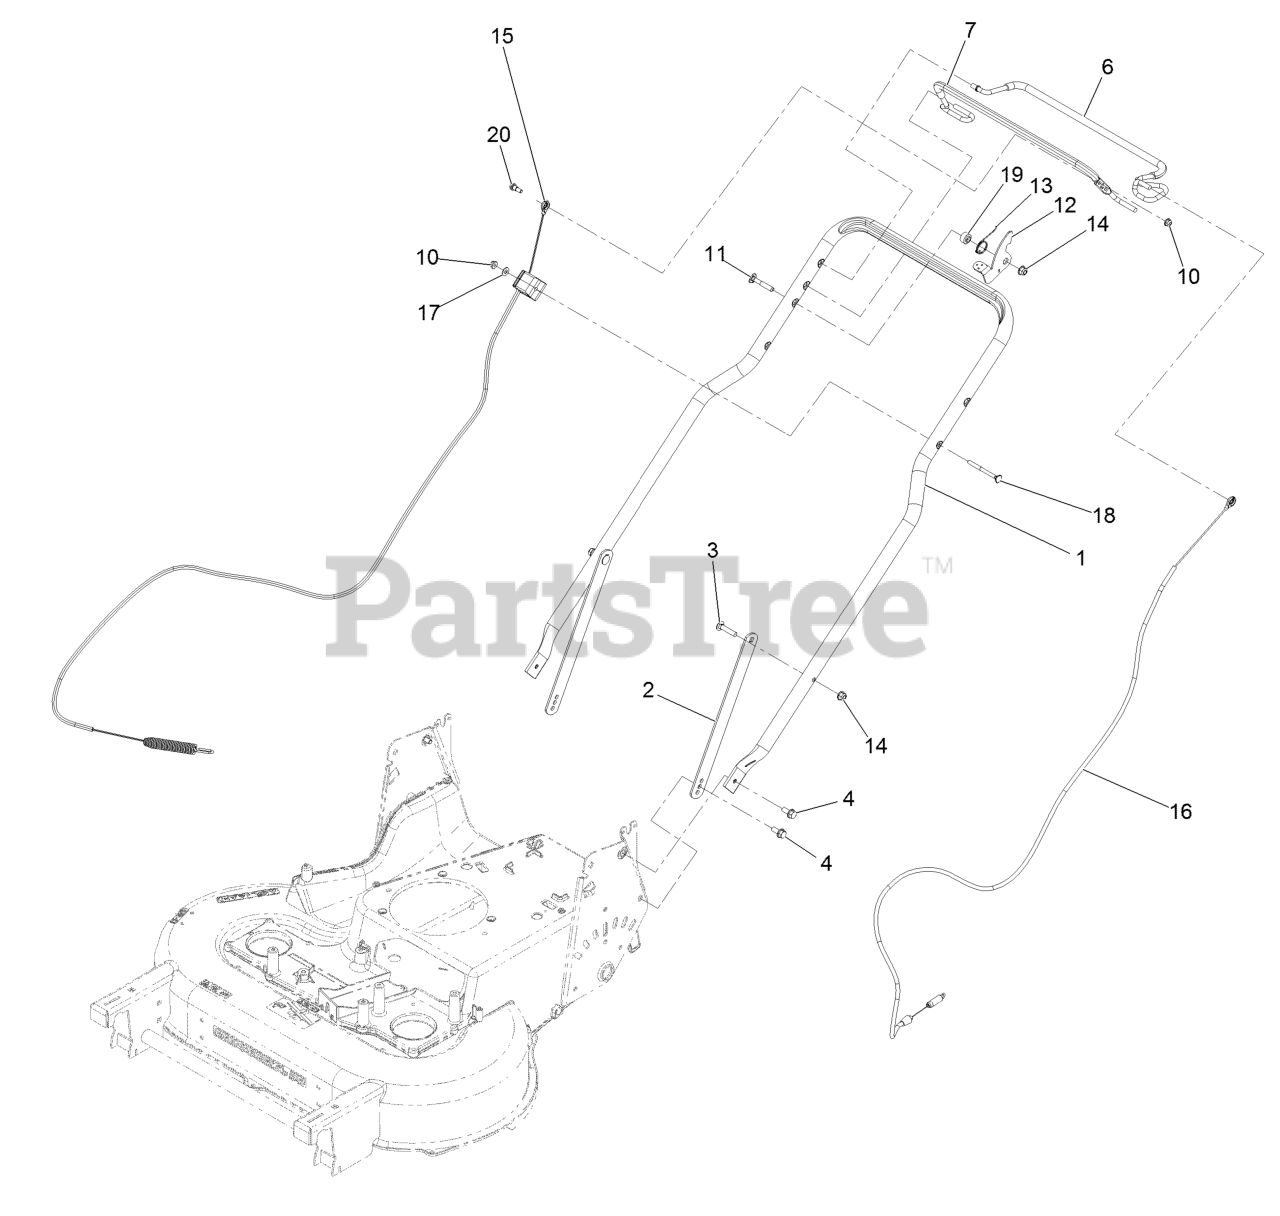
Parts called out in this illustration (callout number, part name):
2	Support-Handle
3	Bolt-Carriage 5/16-18 X 1 1/2
4	Screw-HHF
6	Bail-Traction, Coated
7	Bail-BBC, Coated
10	Nut-Nyloc 1/4-20 Flg
11	Bolt-Carriage 5/16-18 X 2
12	Lever-BBC
13	Spring-Lever, BBC
14	Nut-Nyloc 5/16-18 Flg
15	Cable-BBC
16	Cable-Traction
17	Washer-Flat
18	Screw-Handle
19	Bushing-Stepped
20	Bolt-Shoulder
99	Tie-Cable
